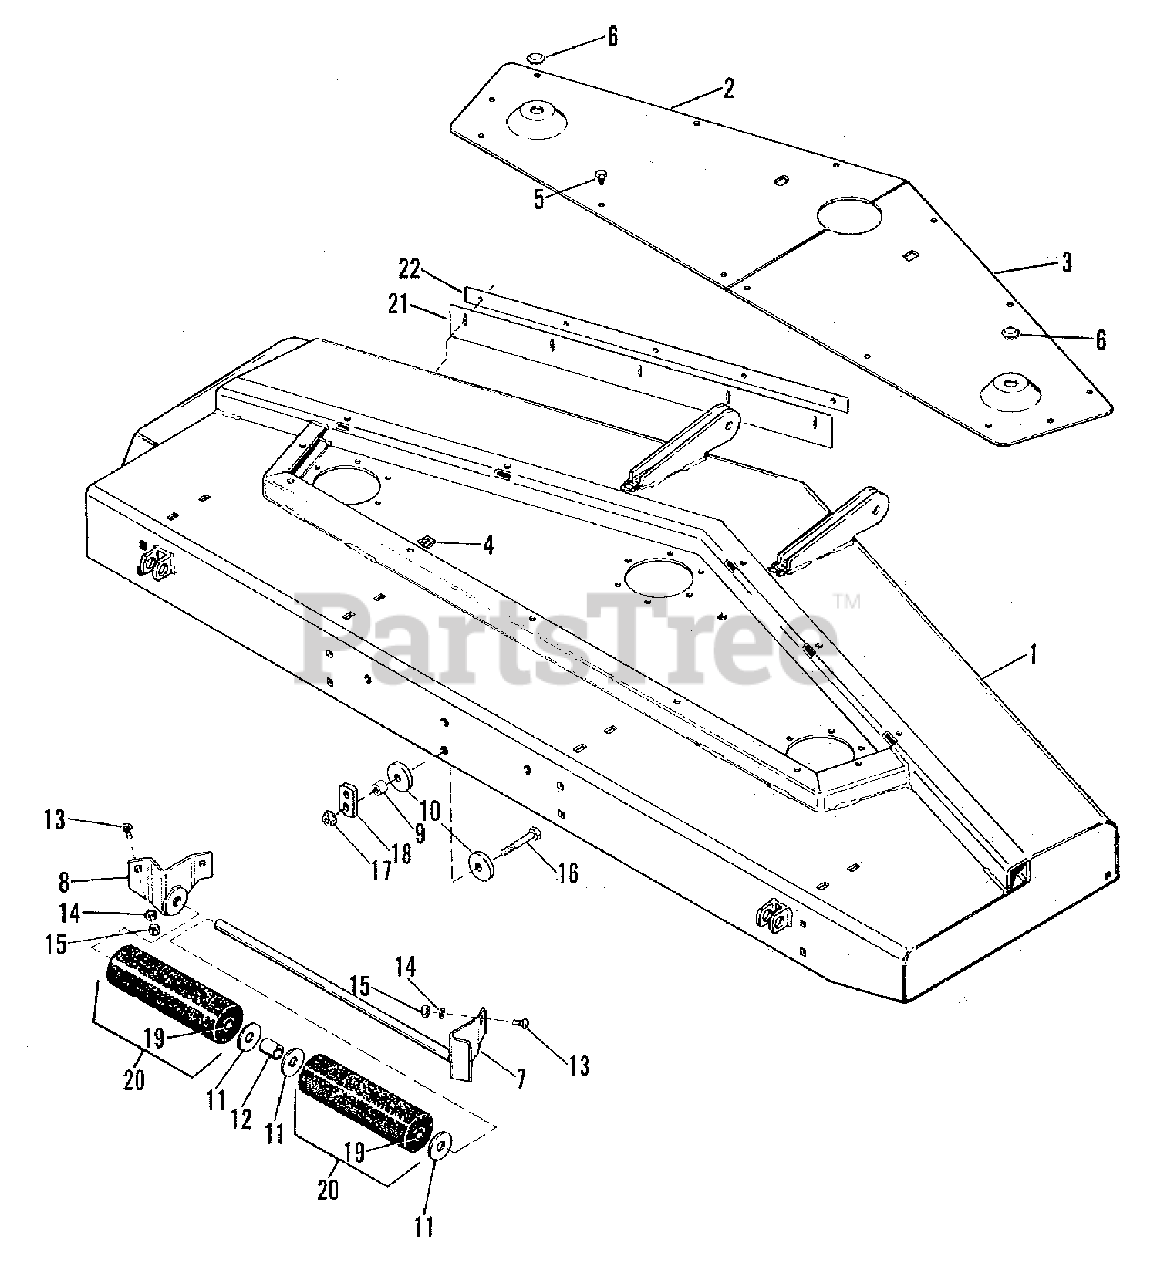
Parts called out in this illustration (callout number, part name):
1	DECK ASSEMBLY, 60" (L.H. Discharge)
2	PLATE, Cover, R.H.
3	PLATE, Cover, L.H.
4	NUT, Speed, Tinnerman
5	SCREW, Tapping, 5/16NC x 7/8
6	BUTTON, Plug
7	BRACKET & SHAFT ASSEMBLY
8	BRACKET ASSEMBLY
9	SPACER (L.H. Discharge)
10	WASHER, Special (L.H. Discharge)
13	BOLT, Carriage, 5/16NC x 3/4
14	LOCKWASHER, 5/16
15	NUT, 5/16NC
16	CAPSCREW, Hex Head, 3/8NC x 1-3/4 (L.H. Discharge)
17	NUT, Centerlock, Flange, 3/8NC (L.H. Discharge)
18	BRACKET (L.H. Discharge)
21	CURTAIN, Grass Deflector
22	PLATE, Deflector Curtain
